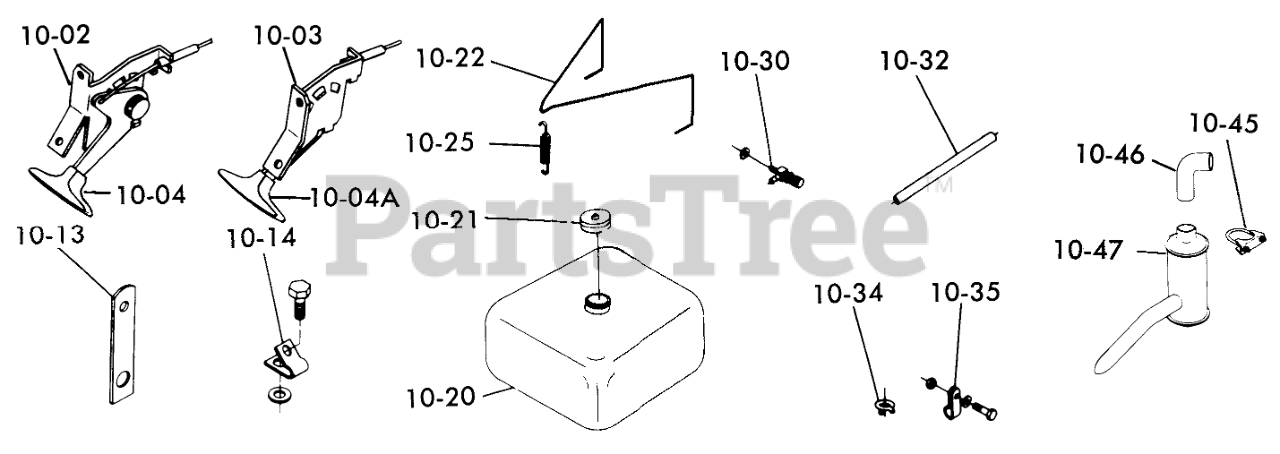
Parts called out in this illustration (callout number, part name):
10-04	KNOB-CHOKE
10-04A	KNOB-THROTTLE
10-14	THROTTLE CONTROL CLP
10-22	HOLD DOWN WIRE
10-30	VALVE-FUEL
10-45	ASSY-MUFFLER CLAMP
10-47	MUFFLER
